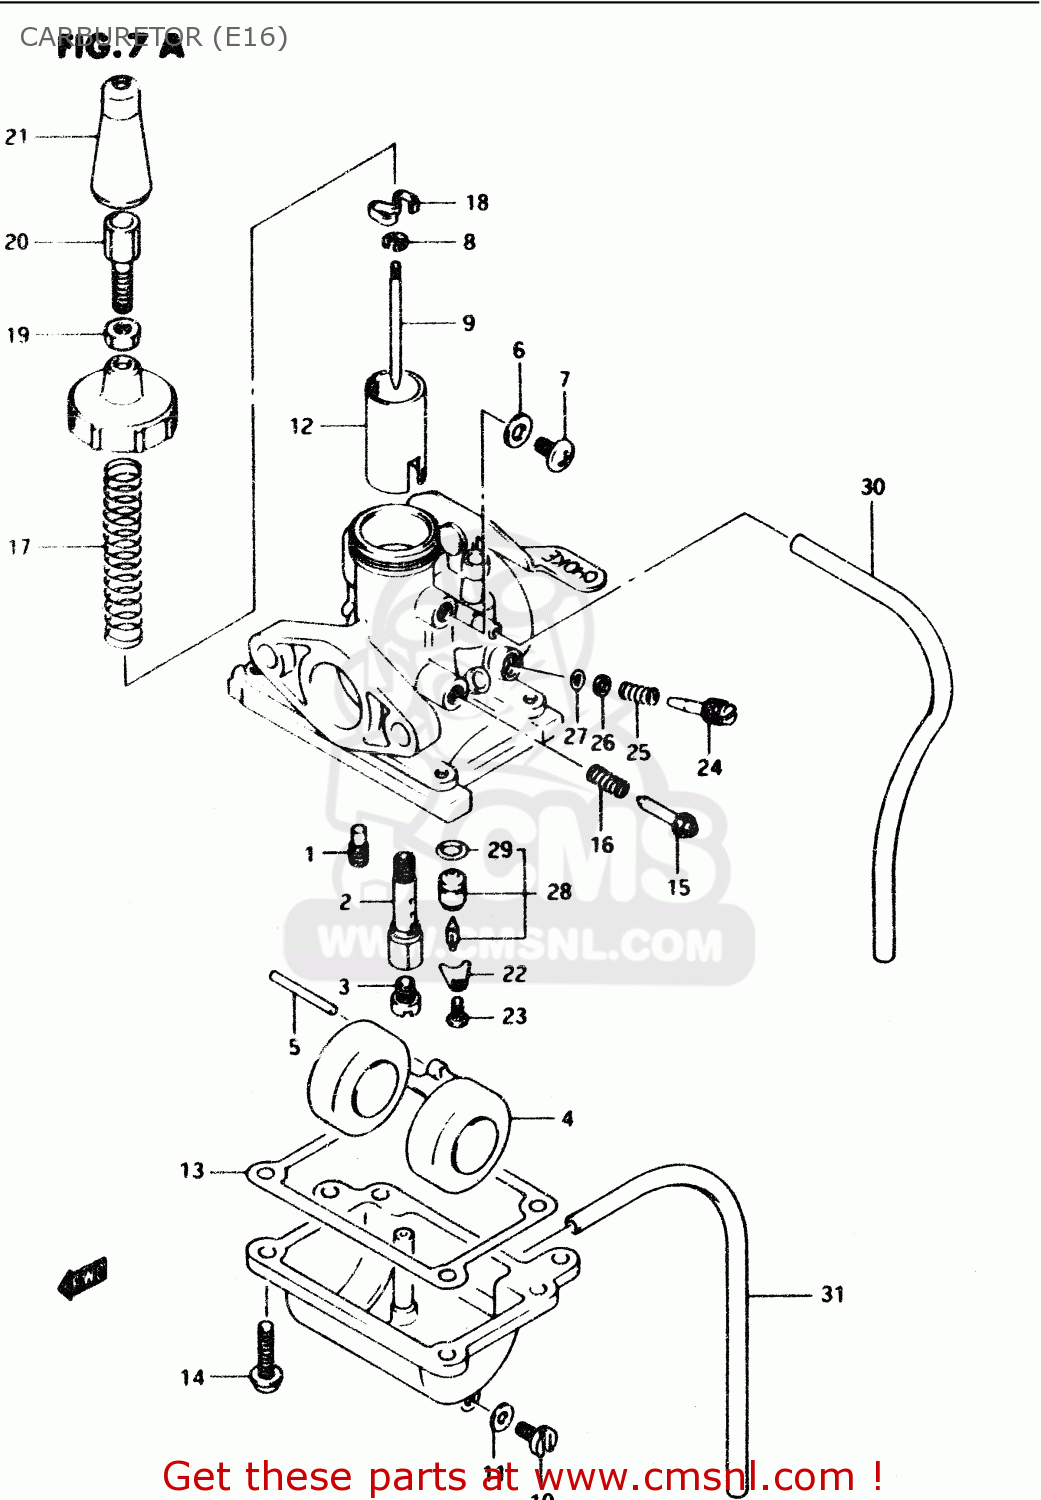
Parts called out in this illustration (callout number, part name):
1	JET,PILOT (17.5)
2	JET,NEEDLE(E-3)
3	JET, MAIN (57.5)
4	FLOAT
5	PIN,FLOAT
6	GASKET,DRAIN PLUG (NAS)
7	SCREW
8	CLIP,NEEDLE
9	NEEDLE,JET
10	PLUG
11	GASKET,DRAIN,PLUG (NAS)
12	VALVE,THROTTLE
13	GASKET (NAS)
14	SCREW
15	SCREW,THROTTLE STOP
16	SPRING
17	SPRING,THROTTLE VALVE RETURN
18	PLATE
19	NUT
20	ADJUSTER,CABLE
21	CAP,RUBBER
22	PLATE,NEEDLE VALVE FITING
23	SCREW
24	SCREW,AIR
25	SPRING
26	WASHER
27	O RING,PILOT AIR SCREW
28	VALVE ASSY,NEEDLE
29	O RING
30	HOSE
31	HOSE
